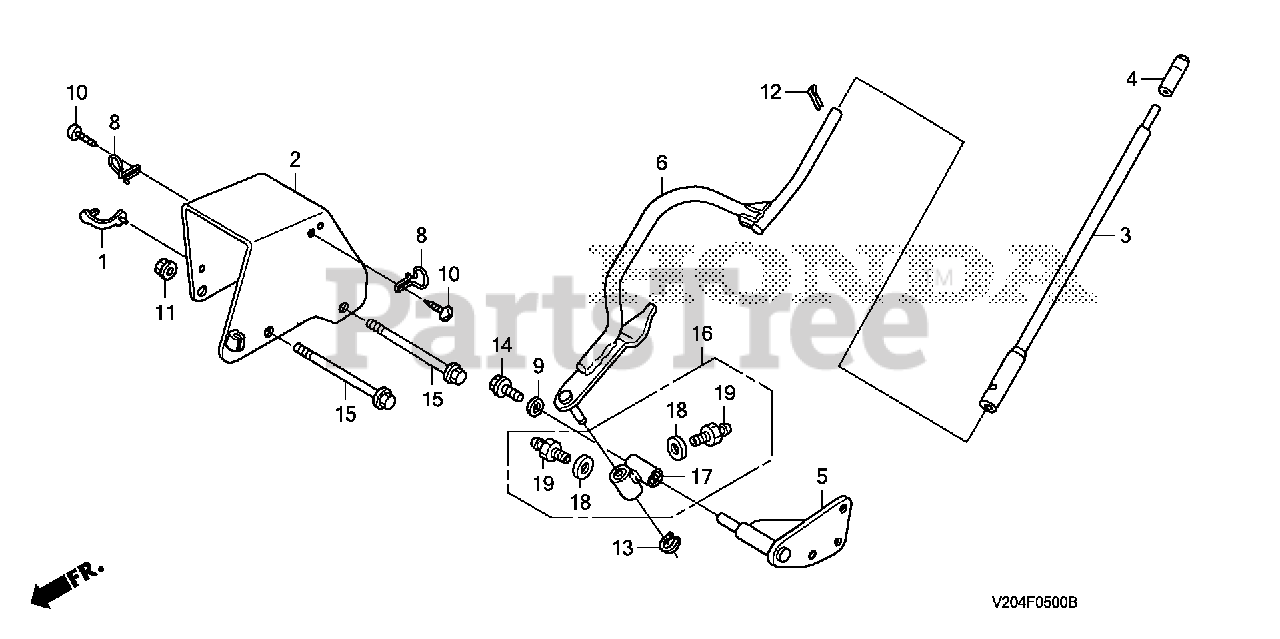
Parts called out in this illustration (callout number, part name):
2	COVER, CHANGE *R280* (POWER RED)
3	LEVER, CHANGE *NH105* (MAT BLACK)
4	GRIP, CHANGE LEVER
5	SHAFT, CHANGE LEVER
6	LEVER, SELECT *NH105* (MAT BLACK)
8	GUIDE, CABLE (LOWER)
9	WASHER, PLAIN (8MM)
10	SCREW, TAPPING (5X10)
11	NUT, FLANGE (10MM)
12	PIN, SPLIT (3.0X45)
13	CIRCLIP, OUTER (12MM)
14	BOLT, FLANGE (8X16)
15	BOLT, FLANGE (10X150)
17	HOLDER, SELECT LEVER
18	WASHER, PLAIN (6MM)
19	NIPPLE, GREASE (A.T6) (M6X1.0)
